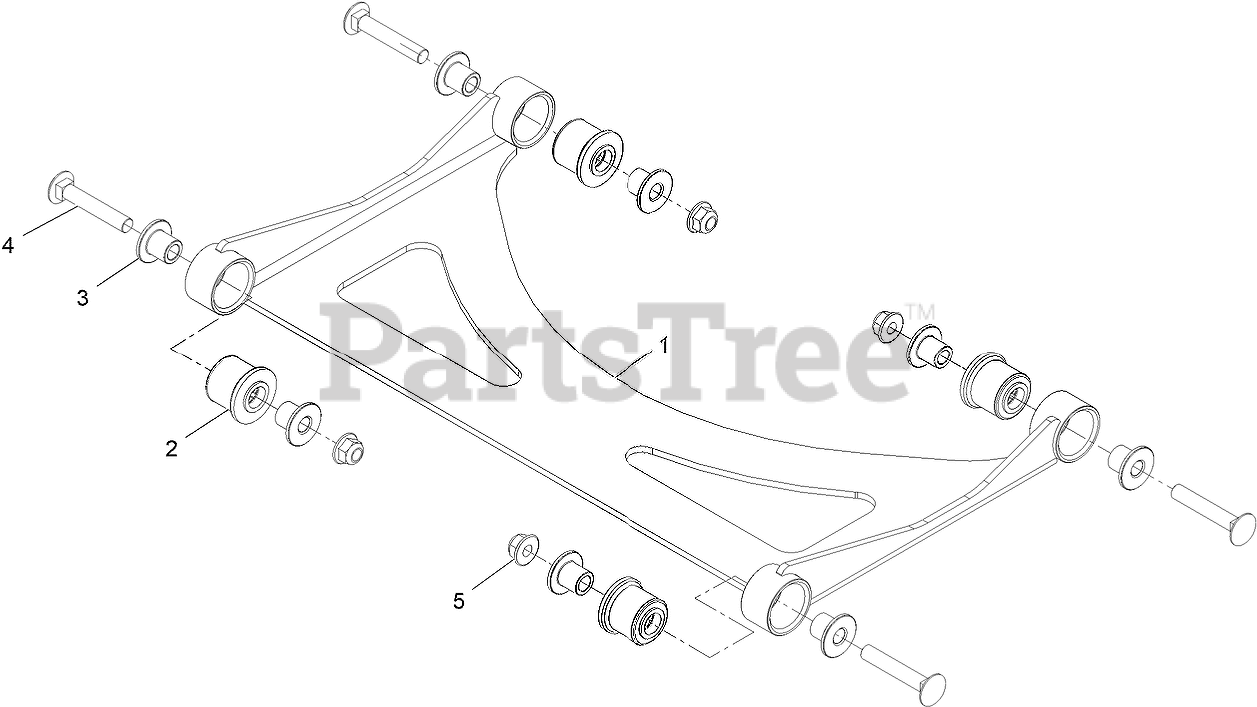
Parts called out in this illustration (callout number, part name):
1	Weld, Deck Strut
2	BUSHING-RUBBER
3	SPACER, STRUT
4	Bolt-Carriage 3/8-16 X 2 1/4
5	NUT-HF, NI
